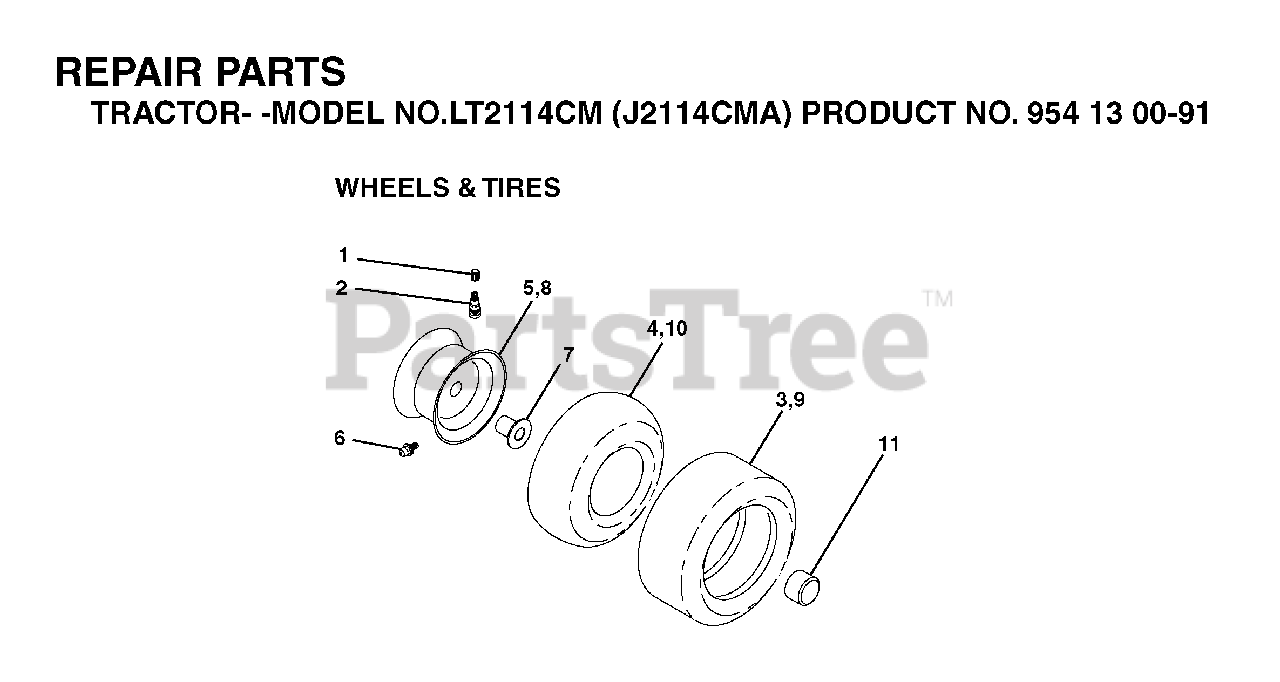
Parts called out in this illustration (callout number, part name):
1	VALVE CAP
2	VALVE STEM LT
3	TIRE HEAVY DUTY
4	TUBE.5.3/4.5/6
5	RIM ASM 6" FRONT SILVER
6	FITTING LT
7	BEARING T
8	RIM ASM 8" REAR SILVER
9	TIRE
10	TUBE
11	CAP, AXLE BLK
